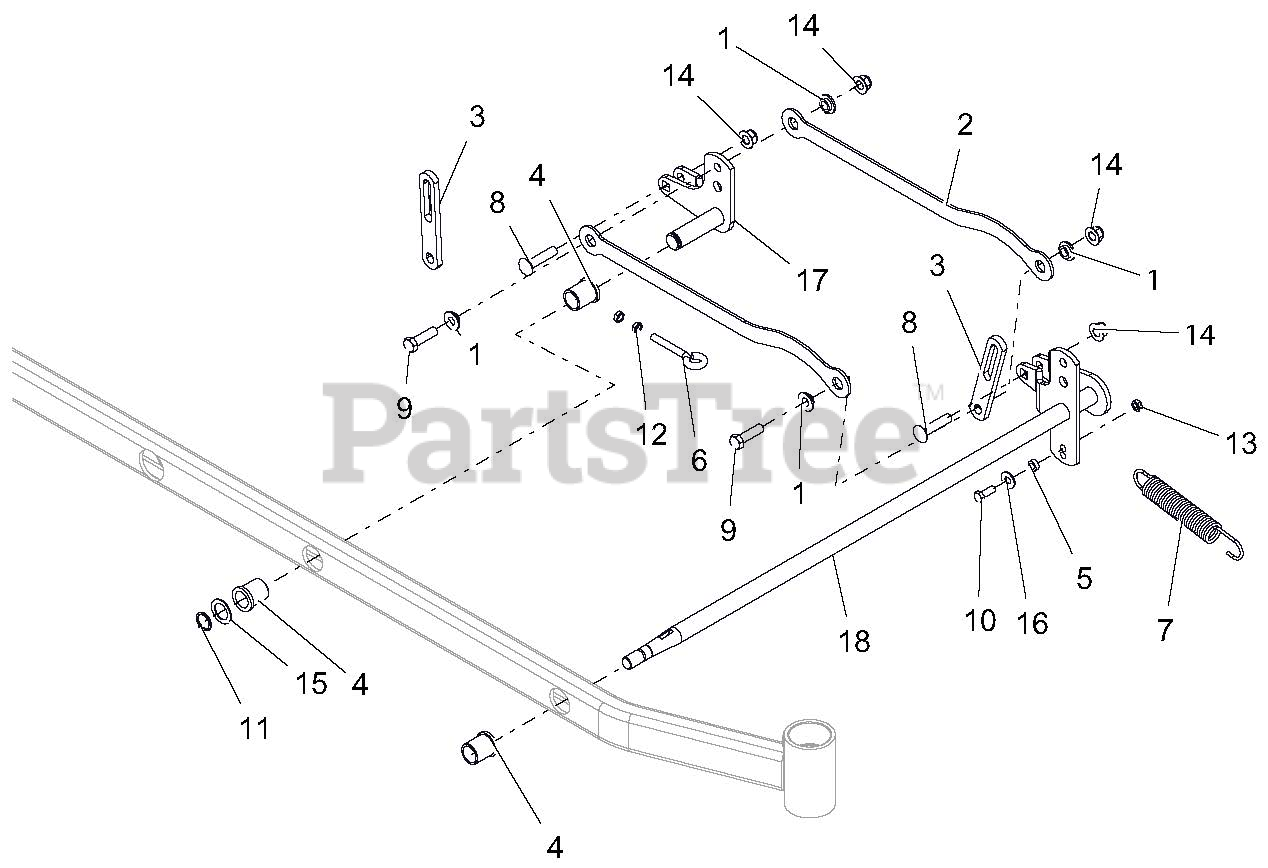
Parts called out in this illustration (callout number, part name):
1	BSHG, FLANGE .515X.750X.31X1.12
2	LINK, LIFT - BLK
3	LINK, DECK LIFT - LONG
4	BSHG-FLG 1.00X1.25X1.5X1.5
5	BSHG, SLV .377X.624X.235
6	BOLT, EYE .375-16
7	SPRG, TENSION .162 X 1.250 X 8.250
8	BLT-RDHDSQNK .50-13X2.25 G5Y
9	BLT-HEX .50-13X1.75 GR5 YWZC
10	BLT-HEX .38-16X1.00 GR5 YWZC
11	RG-RTNG-EXT 1.00X.078
12	NUT, JAM .375-16 YWZC
13	@ NUT-LK-CTR-JAM .375-16 YWZC
14	NUT-LK-NYL-FLG .50-13 YWZC
15	WSHR-FL-STL 1.010X1.505X.062 YWZC
16	WSHR-FL-STL.438X1.00X.083 YWZC
17	WLDMT, LH REAR DECK LIFT
18	WLDMT, PT200 FRONT LH DECK LIFT ARM
